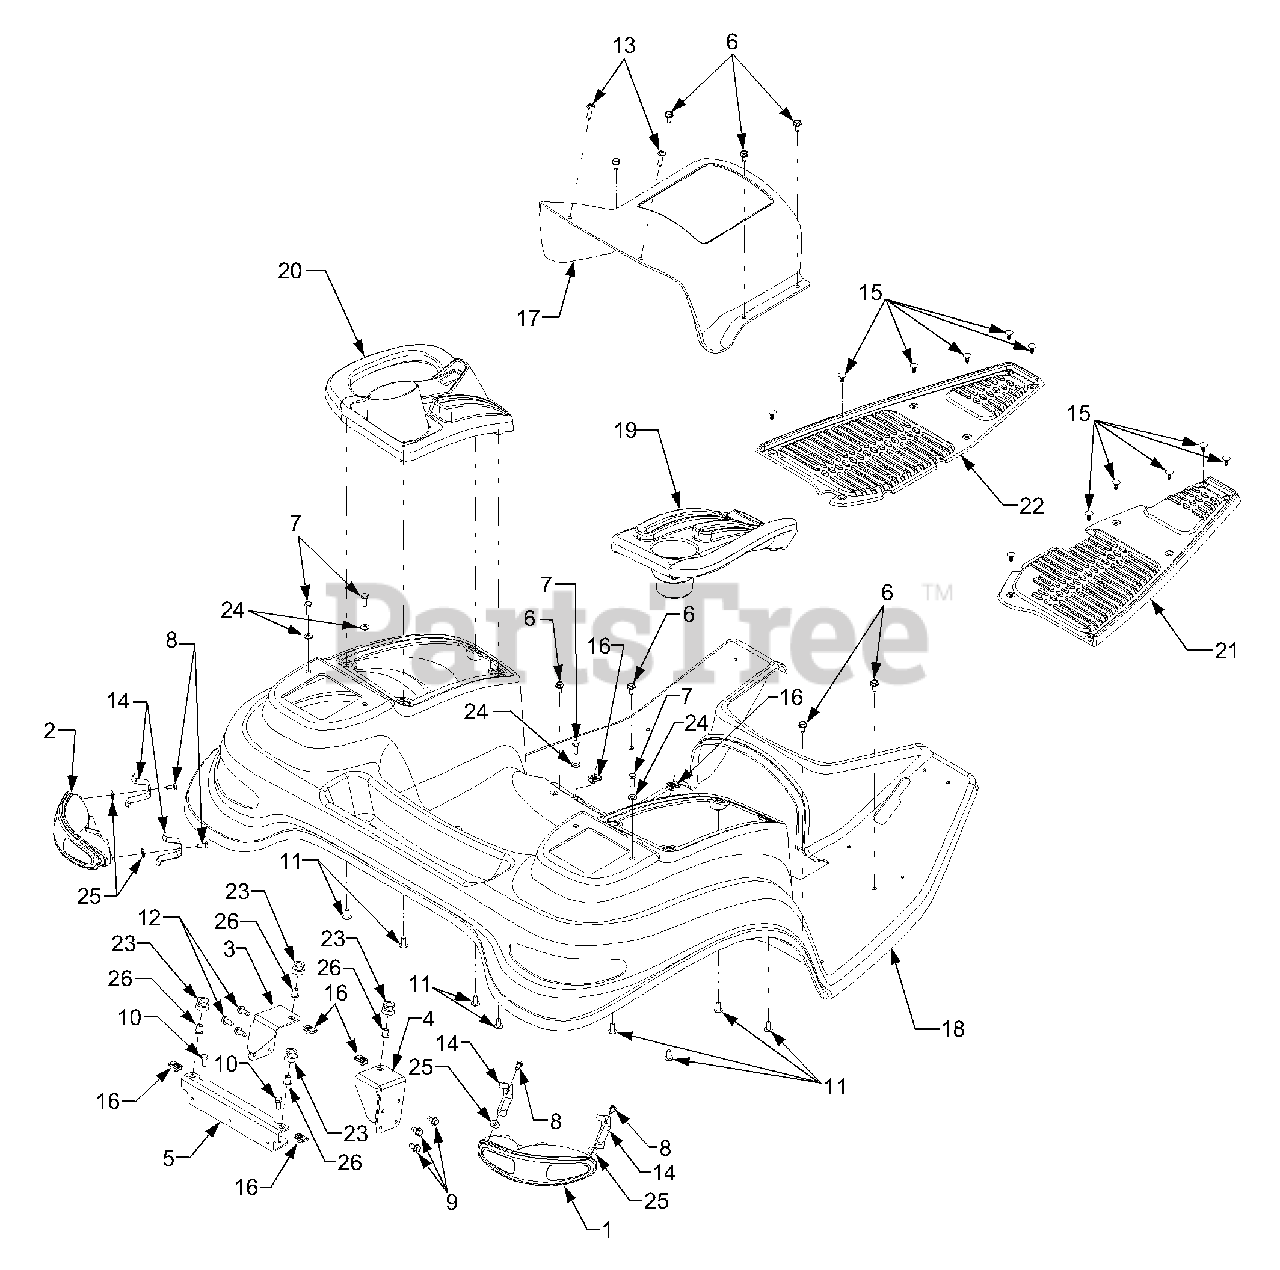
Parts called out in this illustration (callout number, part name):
1	Light Assembly, Rear RH
2	Light Assembly, Rear LH
3	Bracket, Seat Mtg. LH
4	Bracket, Seat Mtg. RH
5	Bracket, Rear Seat Support
6	Screw, Hex Wash Hd. Tapp 5/16-18 x .625
7	Screw, Hex Cap 5/16-18 x .875 GR5
8	Screw, Hex Cap 1/4-20 x .620 GR5
9	Screw, Hex Wash Hd. Tapp 5/16-18 x .625
10	Screw, Hex Cap 5/16-18 x .75 GR5
11	Screw, Truss Phillips Hd 5/16-14 x .75
12	Screw, Hex Wash Hd. Tapp 5/16-18 x .75
13	Screw, Pan Hd. 5/16-18 x 1.0
14	Clip, Tail Light
15	Clip, Ratchet Fastener
16	Speed Nut, "U" Type, 5/16-18
17	Cover, Fender
19	Cover, Fender, RH
20	Cover, Fender, LH
21	Pad, Floor, RH
22	Pad, Floor, LH
23	Grommet, .4375 ID x .75
24	Washer, Flat, .345 x 1.0 x .100
25	Washer, Flat, .28 x .74 x .063
26	Spacer, Flange, .3125 x .4375 x .625
